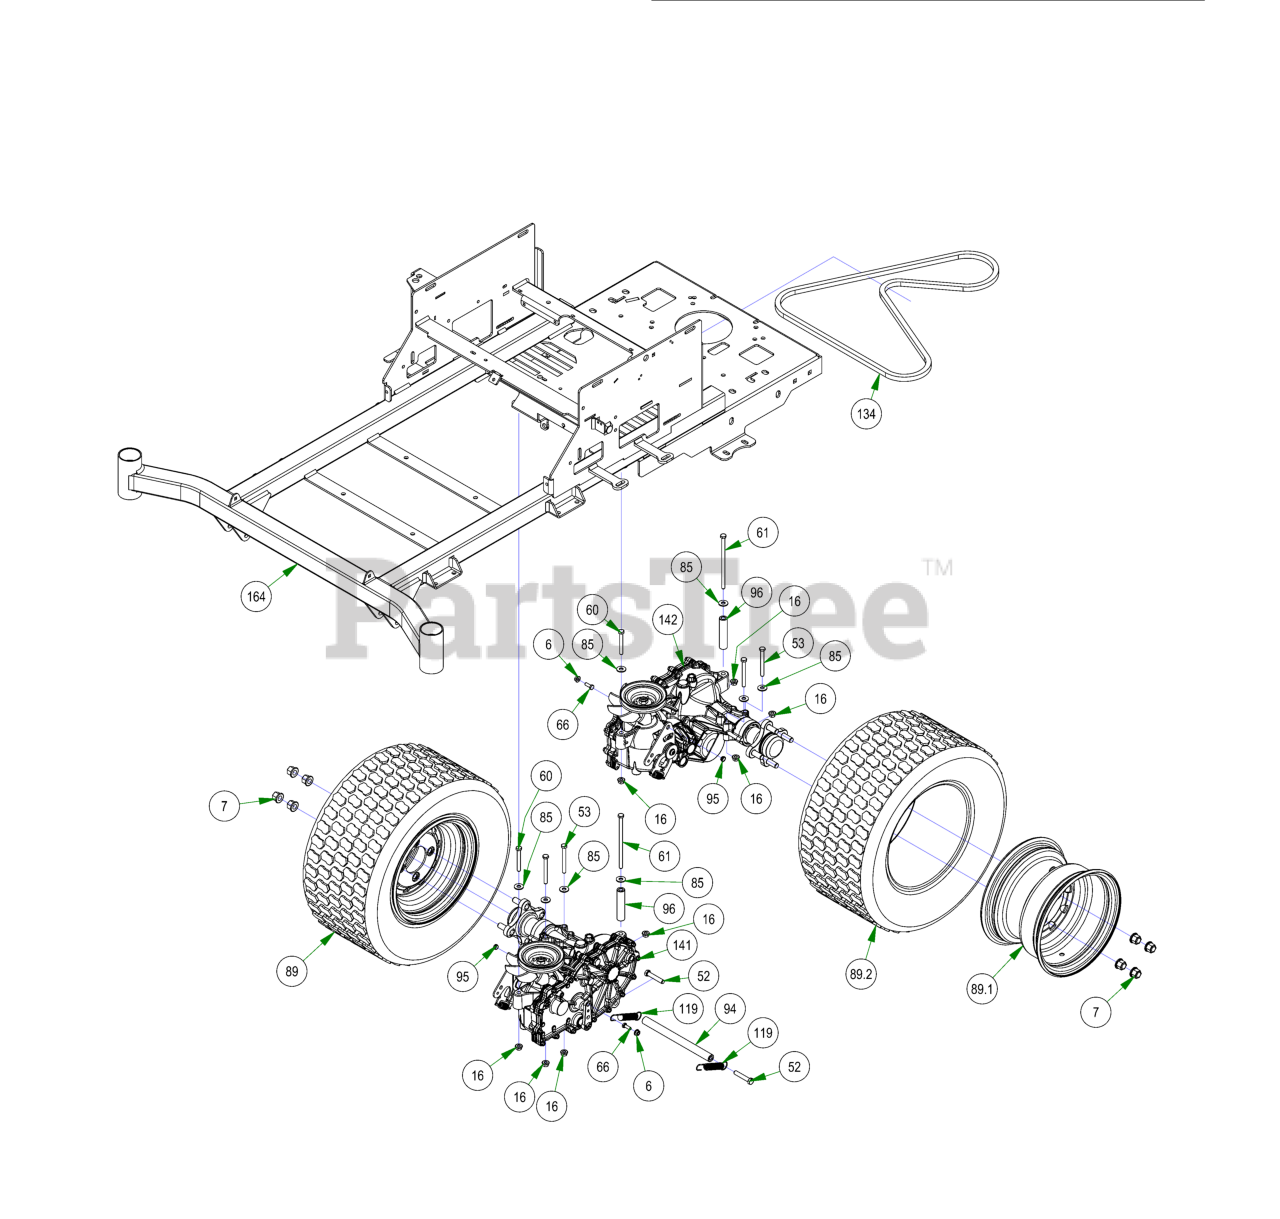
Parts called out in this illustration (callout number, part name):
6	1/4-20 NYL INSERT FLANGE LOCKNUT ZINC
7	Acorn Lug Nut
16	5/16-18 NYLON INSERT FLANGE LOCKNUT ZINC
52	3/8-16 X 2 HEX CAP SCREW (GR.5) ZINC
53	5/16-18 X 3 HEX CAP SCREW (GR.5) ZINC
60	5/16-18 X 2-1/2 HEX CAP SCREW (GR.5) ZINC
61	5/16-18 X 6 HEX CAP SCREW (GR.5) ZINC
66	1/4-20 X 3/4 HEX CAP SCREW (GR.5) ZINC
85	5/16 USS FLAT WASHER (7/8 OD) ZINC
89	20x12x10 Rear Tire & Black Wheel Assembly
89.1	10 x 8.50 Black Wheel for the 022-0008-00
89.2	20x12x10 Rear Tire
94	2017 Transaxle Spacer-ZT
95	Drive Arm Transaxle Spacer
96	2017 Transaxle Spacer
119	Brake Return Spring
141	2021 RH 2800 Transaxle
142	2021 LH 2800 Transaxle
164	2023 MZ-Avenger 54-60 Frame - Painted
